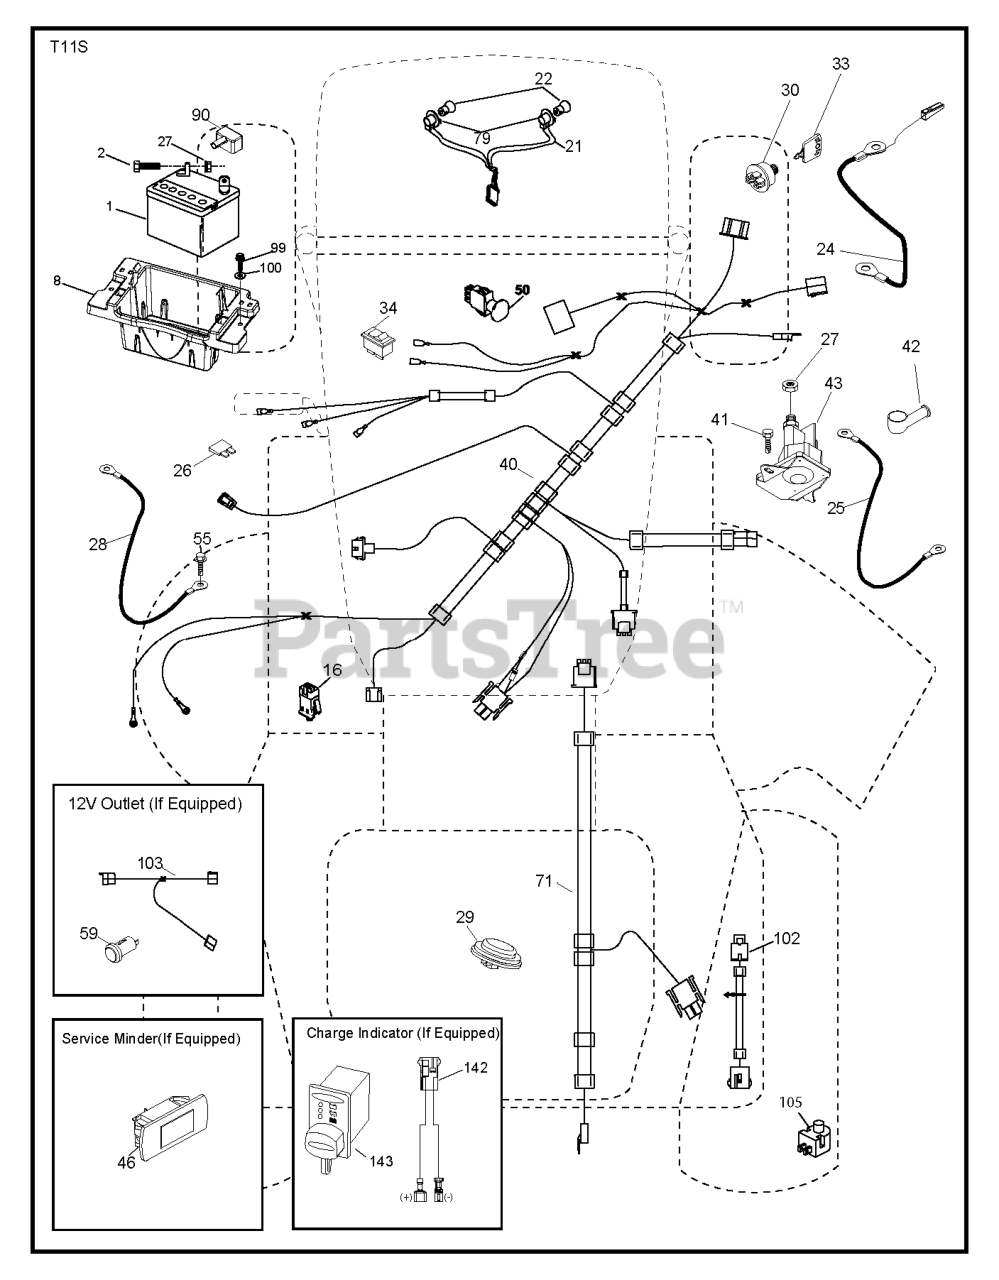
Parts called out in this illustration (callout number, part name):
1	Battery 12 Volt 25 Amp
2	BOLT.HEX.1/4.X.3/4.DICHROMATE
8	TRAY.ASM.BATTERY.FRT.TEX.CARB
8	TRAY.BATTERY BOX.FRONT
16	SWITCH INTERLOOK PUSH-IN
21	HARNESS.LIGHT W/4152J BULBS
24	CABLE.FRBATT.W/WIRE.8GA.8
25	CABLE.STARTER.8GA.17.5
26	FUSE 20AMP
27	NUT
28	CABLE GROUND 6 GA 21" 90T BLK
28	CABLE.GROUND.21"BLK.8GA.90T
29	SWITCH.SEAT.DELTA.OPC.
30	SWITCH.IGN.DELTA.W.LGH.ROS
33	KEY.CHAIN.BLISTER.PACK.GEN.USA
40	HARNESS HARNESS..DASH.ING.ELEC
41	SCREW
42	TERMINAL COVER
43	SOLENOID.STARTER.BRASS.PLUNGER
46	GUAGE.SRVCMNDR.HRMTR.
50	SWITCH.PTO.8TERMINAL.STD.BLK
55	SCREW 5/16"
71	HARNESS-CHASSIS SUB
79	BULB HOLDER ASM.
90	COVER.TERMINAL.BATTERY
99	SCREW HEXWSHR 1/4-20X3/4
102	HARNESS.PIGTAIL.VARIATOR.SD
105	REVERSE SWITCH
